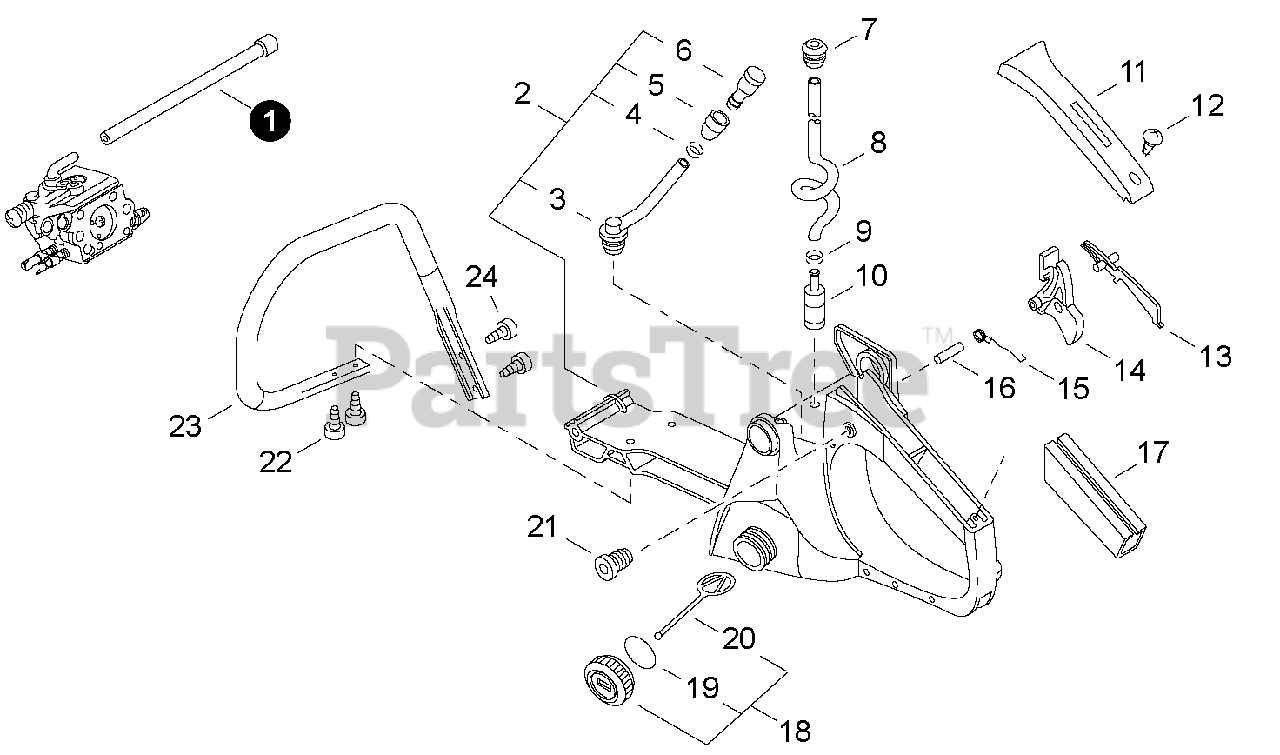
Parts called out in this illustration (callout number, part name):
1	PIPE, FUEL 3×6×105 BLACK
2	HANDLE ASSY, REAR
3	PIPE, VENT 3×6×65
4	CLIP Ø6.5 MM
5	HOLDER, VENT
6	VENT ASSY
8	PIPE, FUEL 3×5×250
9	CLIP 6 MM
10	FILTER, FUEL
11	COVER, HANDLE
12	SCREW 4×14
13	LEVER, THROTTLE LOCKOUT
14	TRIGGER, THROTTLE
15	SPRING, THROTTLE RETURN
16	PIN, SPRING 4×30
17	GRIP, HANDLE
18	CAP ASSY, FUEL
19	O-RING 22
20	CONNECTOR, CAP L= 60 MM
22	SCREW TAPPING 5×16
23	HANDLE, FRONT
24	SCREW TAPPING 5×20
